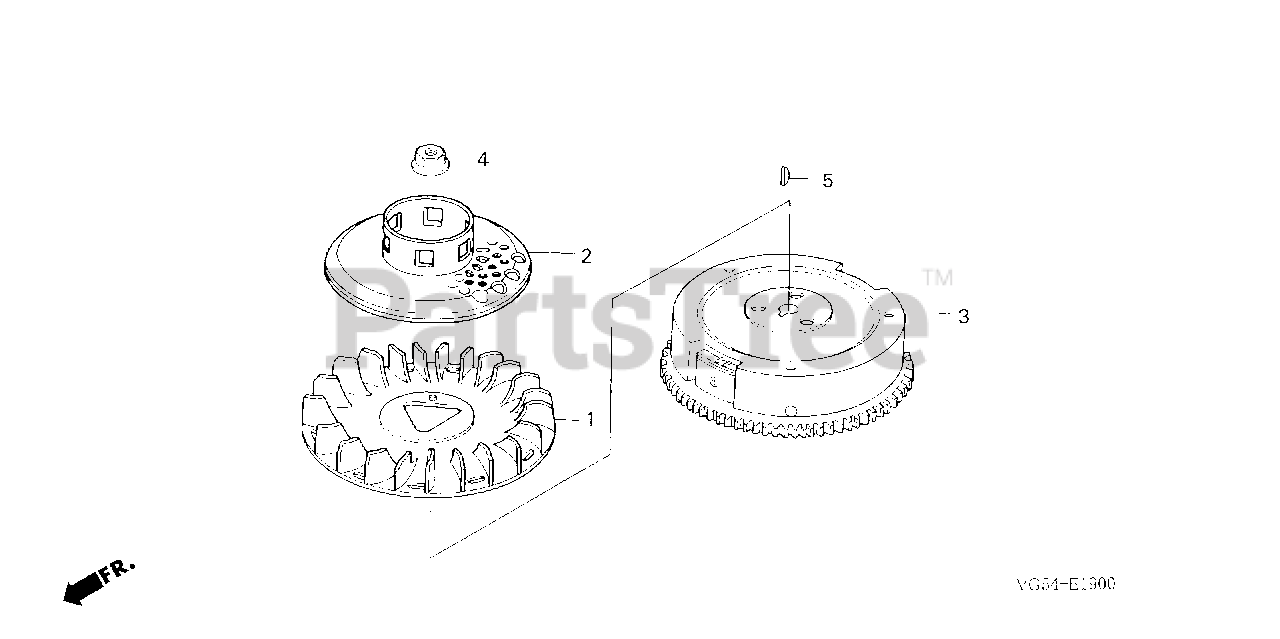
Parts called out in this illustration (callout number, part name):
1	FAN, COOLING
2	PULLEY, STARTER (SCREEN GRID)
3	FLYWHEEL
4	NUT, SPECIAL (16MM) (1)
5	KEY, SPECIAL WOODRUFF (25X18)
